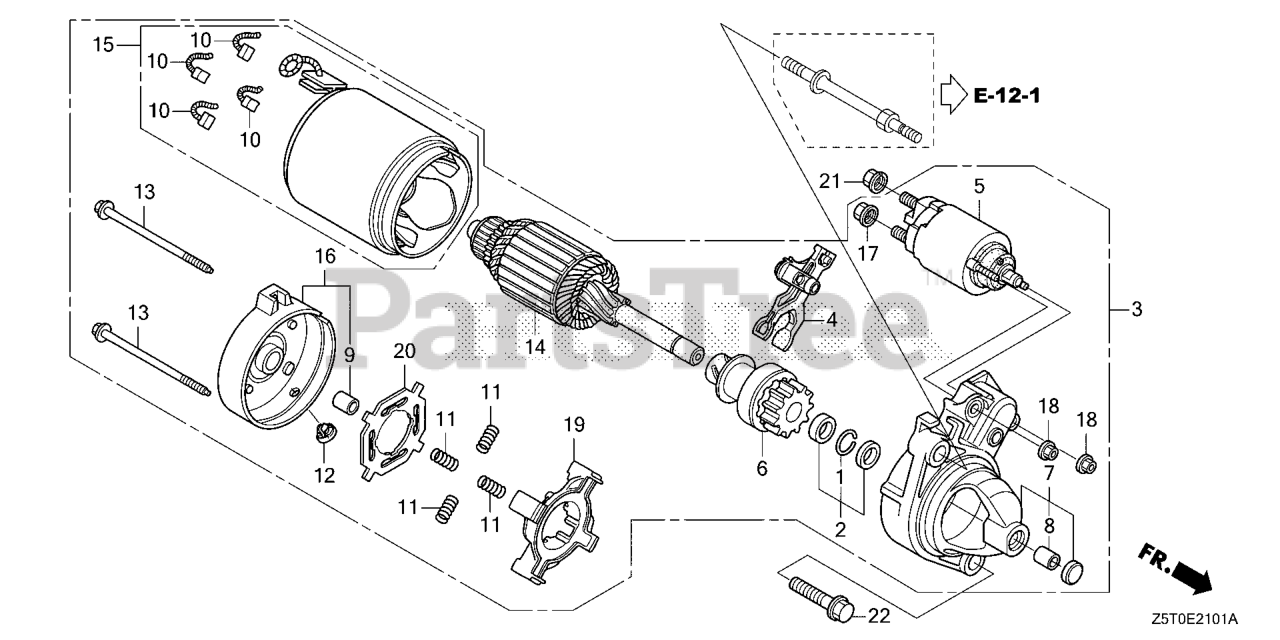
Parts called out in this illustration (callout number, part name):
1	RING, SNAP (DENSO)
2	COLLAR SET, CLUTCH STOP
3	STARTER MOTOR ASSY.
4	LEVER, PINION DRIVE
5	SWITCH ASSY., MAGNET
6	CLUTCH, OVERRUNNING
7	HOUSING, DRIVE SIDE
9	BEARING B
10	BRUSH
11	SPRING, BRUSH
13	BOLT, THROUGH
16	FRAME, COMMUTATOR END
17	NUT, HEX. (8MM)
18	NUT, FLANGE (5MM)
19	HOLDER, BRUSH
20	INSULATOR, BRUSH HOLDER
21	NUT-WASHER (8MM)
22	BOLT, FLANGE (10X40)
